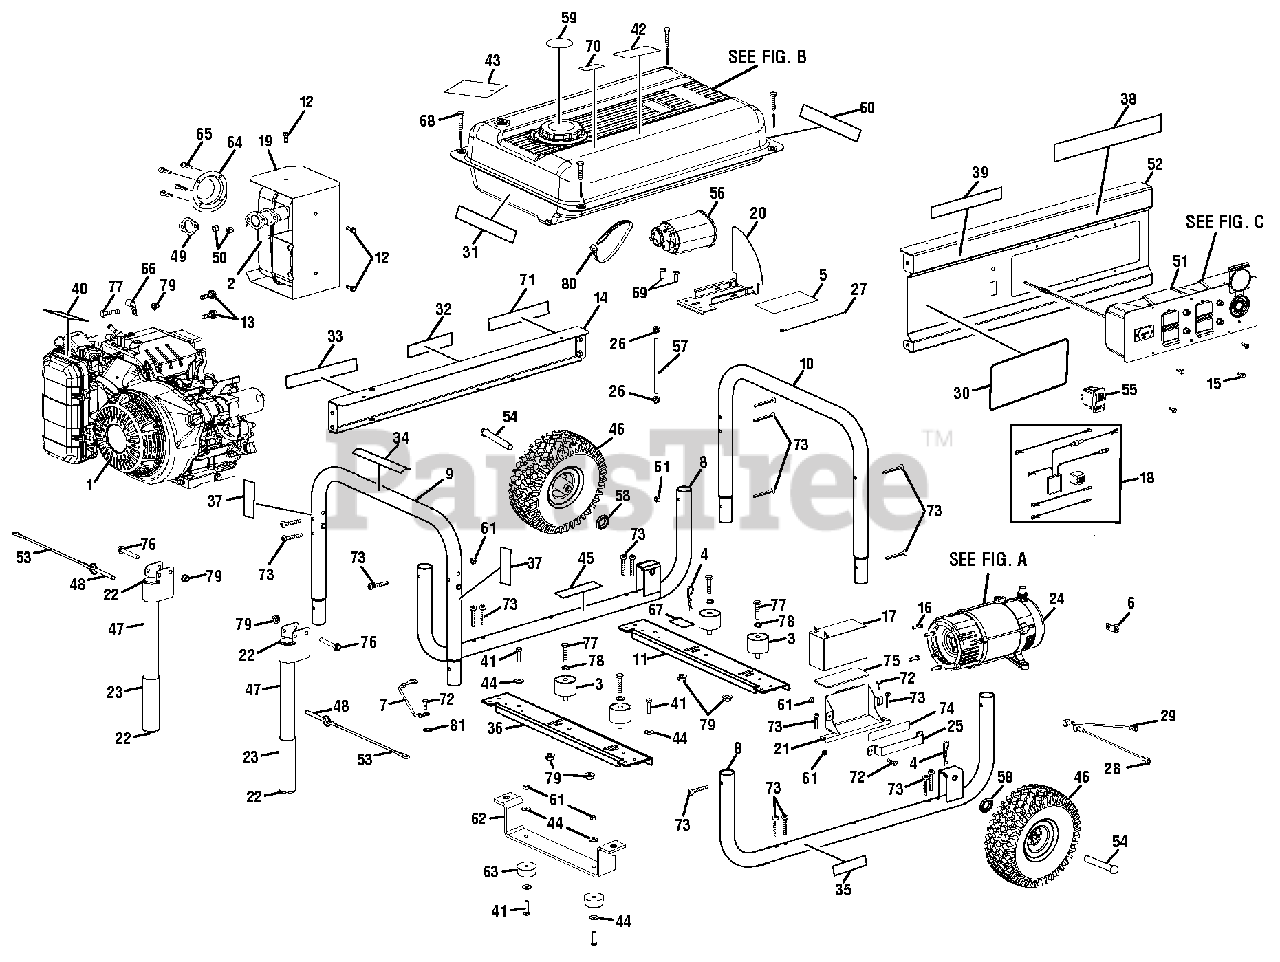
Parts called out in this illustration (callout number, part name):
1	Engine (Honda)
4	Hitch Pin
5	Rubber Sheet
6	Ground Lug
7	Ground Wire Assembly
8	Lower Frame Assembly
9	Tube Assembly (Left)
10	Tube Assembly (Right)
11	Gen. Head Cross Brace
12	Bolt (M6 x 9 mm)
13	Bolt (5/16-24 x 5/8 in.)
14	Back Panel
15	Screw (6-20 x 3/8 in.)
16	Bolt (3/8-16 x1.25 in.)
17	Battery
18	Wire Harness
19	Heat Shield
20	Bracket (Carbon Canister)
21	Battery Box
22	Plastic Cap
23	Handle Grip
24	Generator Head w/AVR
25	Battery Bracket Assembly
26	Clamp (1/2 in.)
28	Battery Cable (Red)
29	Battery Cable (Black)
30	Logo Label
31	Electric Start Label
32	Hot Surface Label
33	Danger Label
34	Fire Danger Label
35	Engine Lubricant Label
36	Engine Cross Member
37	Locking Pin Label
38	Honda Label
39	Electric Start Label
40	Choke Label
41	Bolt (M6 x 1 in., Hex Hd.)
42	CPSC Label
43	Danger Hang Tag
44	Washer (ID6.4 x OD17 x 1.6t)
45	Combustion Warning Label
47	Handle Assembly
48	Release Pin (5/16 x 2 in.)
49	Exhaust Gasket
50	Lock Nut (M8)
51	Panel Assembly
52	Front Panel
55	Start Switch w/Lock
56	Carbon Canister Assembly
57	Purge Hose
58	Washer (1/2 in.)
59	Fuel Stabilizer Label
60	Ground Warning Label
61	Lock Nut (M6)
62	Foot Bracket
63	Rubber Foot
64	Spark Arrestor
65	Screw (8-32 x 3/8 in., Pan Hd.)
66	J-Clamp (1/2 in.)
67	Ground Label
68	Screw (1/4-14 x 1-1/4 in.)
69	Screw (#10-16 x 3/4 in.)
70	E85 Label
71	Fire Distance Label
72	Screw (M6 x 16 mm, Hex Hd.)
73	Screw (M6 x 50 mm, T30, Pan Hd.)
74	Hold Down Gasket
75	Battery Tray Gasket
76	Bolt (M8 x 55 mm, Hex Hd.)
77	Bolt (M8 x 35 mm, Hex Hd.)
78	Washer (M8)
79	Lock Nut (M8)
80	Cable Tie (5.5 in, blk)
81	Star Washer (M8)
